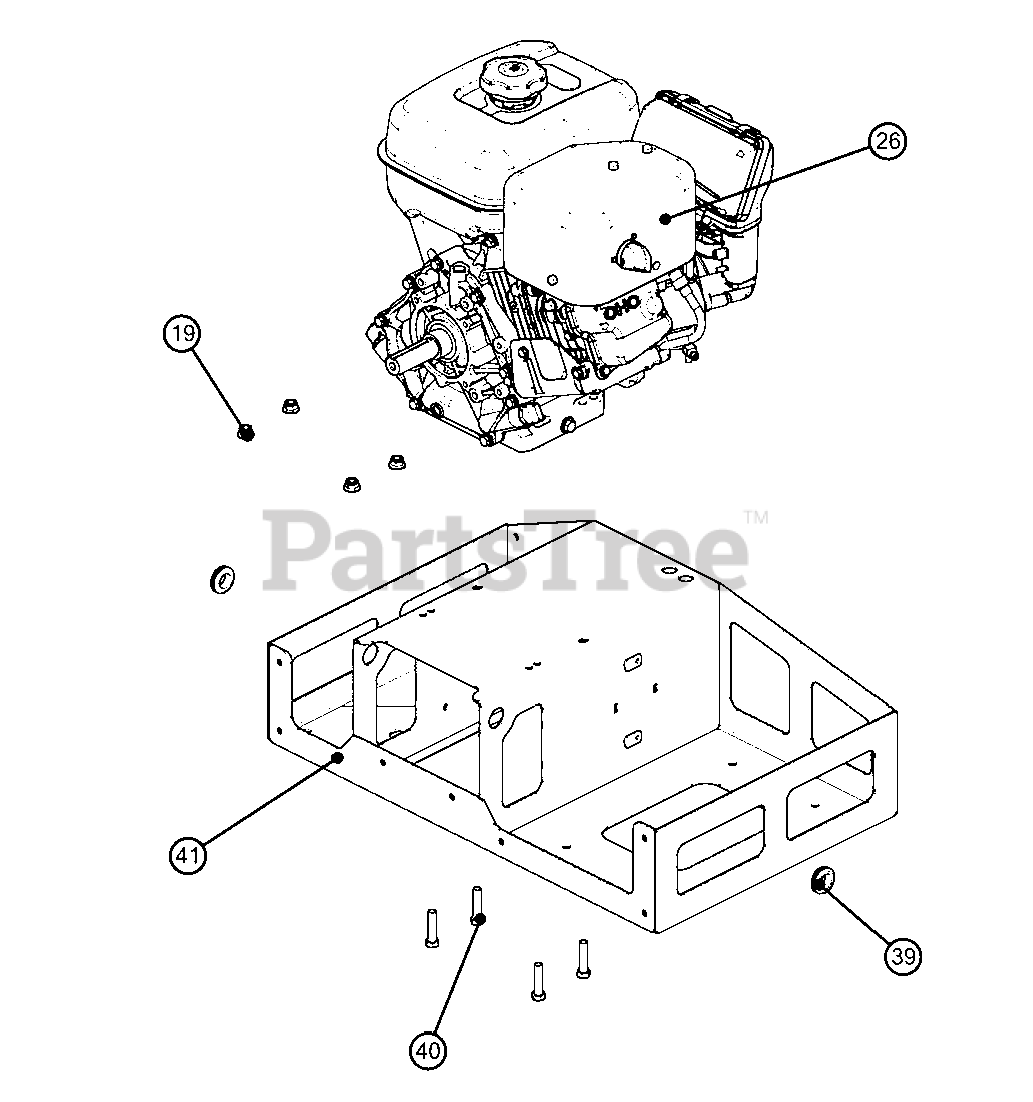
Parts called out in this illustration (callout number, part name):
19	Nut, Nyloc Flange .38-16 YWZC
26	Engine, Robin EX40 14 HP
39	Grommet, Rubber .88 ID x 1.38 OD x .14 GR
40	Bolt, Hex .38-16 x 1.75 Grade 5 YWZC
41	Weldment, Frame Base
